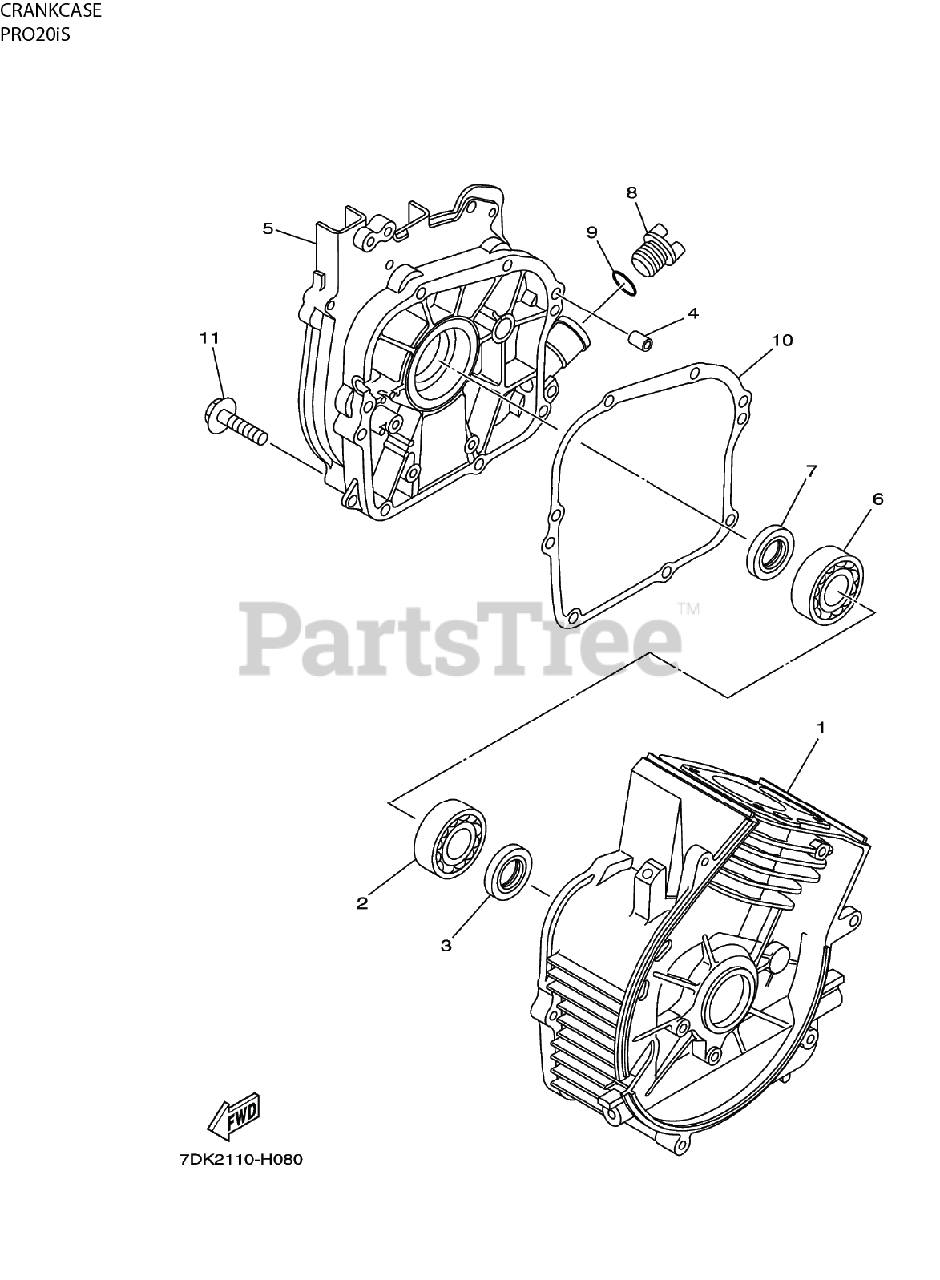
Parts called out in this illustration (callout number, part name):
1	CRANKCASE 1
3	SEAL, OIL
4	CRANKCASE 1
5	PLATE, CLOSURE & BEARING
7	SEAL, OIL
10	GASKET, CRANKCASE COVER 1
11	SCREW - BOLT
